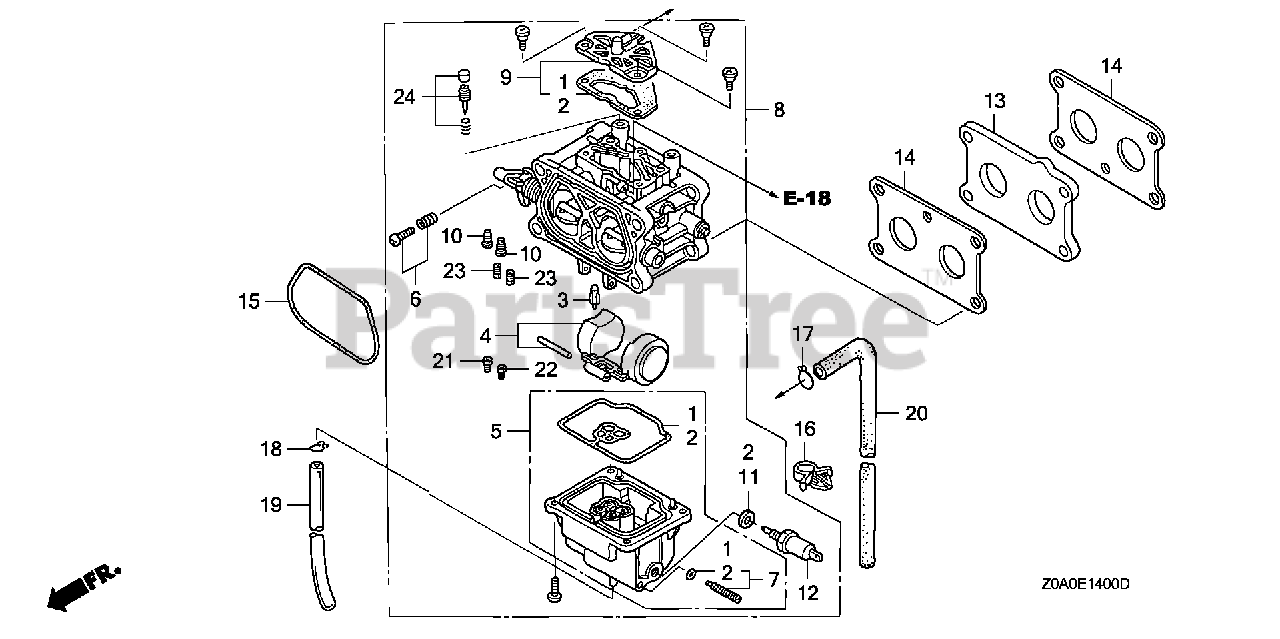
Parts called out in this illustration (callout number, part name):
2	GASKET SET
3	VALVE, FLOAT
5	CHAMBER SET, FLOAT
7	SCREW SET, DRAIN
8	CARBURETOR ASSY. (BW02B C)
9	COVER SET, AIR VENT
12	VALVE ASSY., SOLENOID
13	INSULATOR, CARBURETOR
14	GASKET, INSULATOR
15	GASKET, AIR CLEANER
16	CLIP, WIRE HARNESS
17	CLIP, TUBE (B8)
18	CLIP, TUBE (B6.5)
19	BULK HOSE, VINYL (4X7X8000) (95003-07(95003-07001-60M) (CARBURETOR NO.)
20	BULK HOSE, VACUUM (4.5X1000) (4.5X450) (BULK HOSE 95005-45008-10M)
21	JET, MAIN (#82.5)
21	JET, MAIN (#85)
21	JET, MAIN (#87.5)
22	JET, MAIN (#85)
22	JET, MAIN (#87.5)
22	JET, MAIN (#90)
23	JET, PILOT (#37.5) (CARBURETOR NO.)
24	SCREW SET, PILOT
